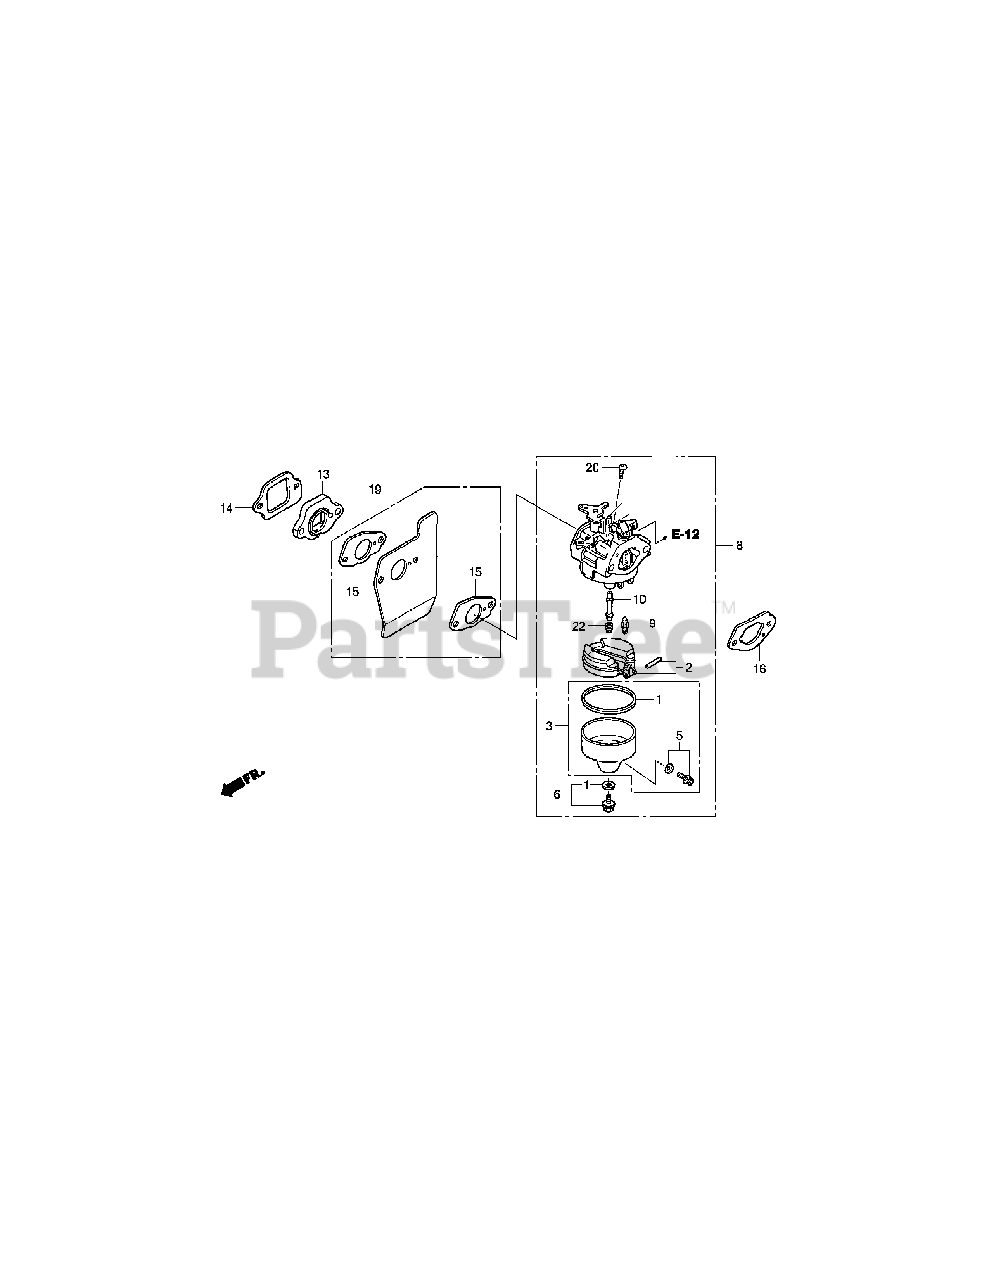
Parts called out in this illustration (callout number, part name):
1	Gasket Set
3	Float Chamber Set
5	Drain Screw Set
6	Screw Set
8	Carburetor Assembly
9	Float Valve
10	Main Nozzle
13	Carburetor Insulator
14	Insulator Gasket
15	Carburetor Gasket
16	Carburetor Gasket
20	Pan Screw, 5 x 6
22	Main Jet, #60
22	Main Jet, #62
22	Main Jet, #65
